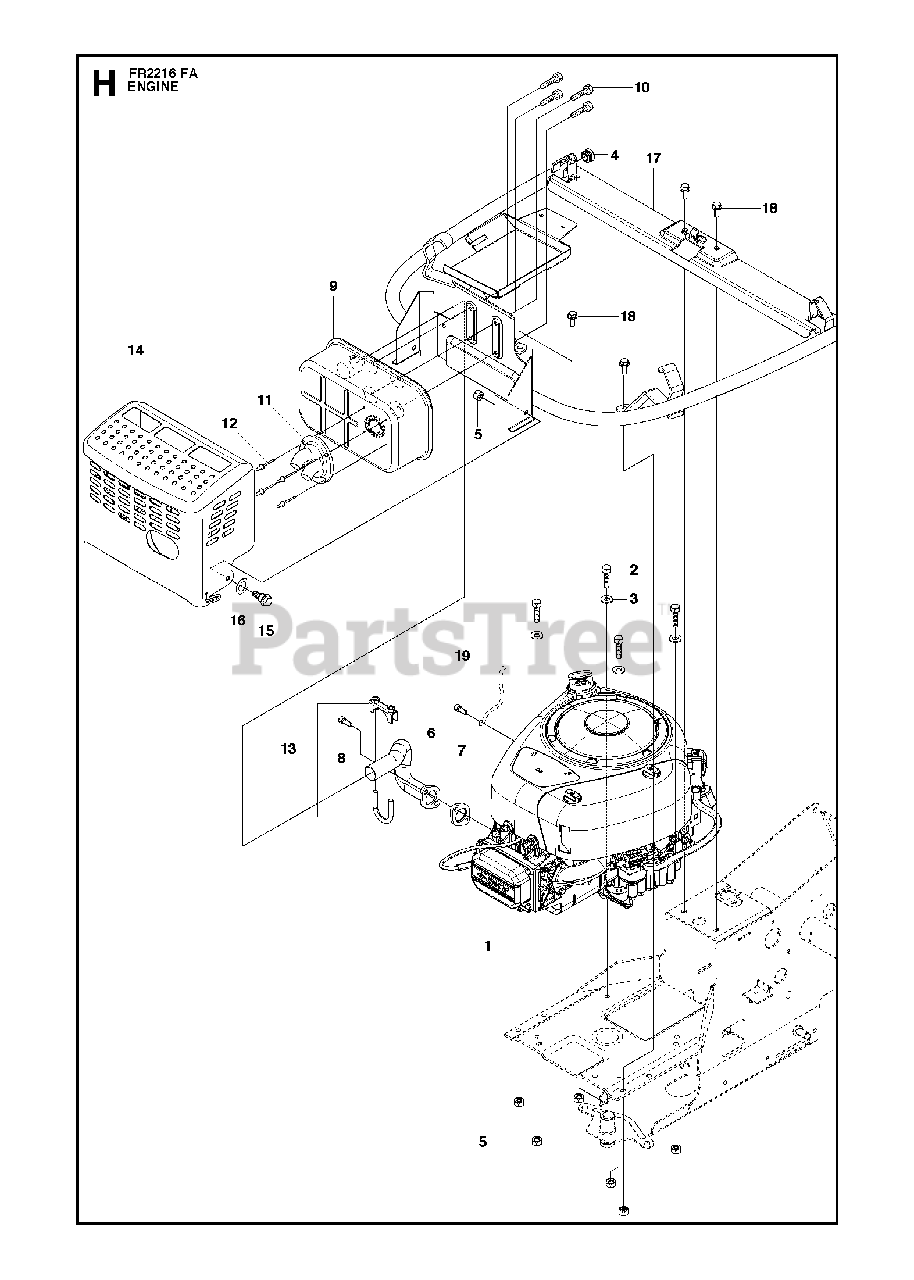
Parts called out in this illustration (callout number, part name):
3	WASHER BRB 8.4X17
5	LOCKNUT M8
9	MUFFLER
10	SCREW
13	CLAMP
16	SPRINGWASHER
